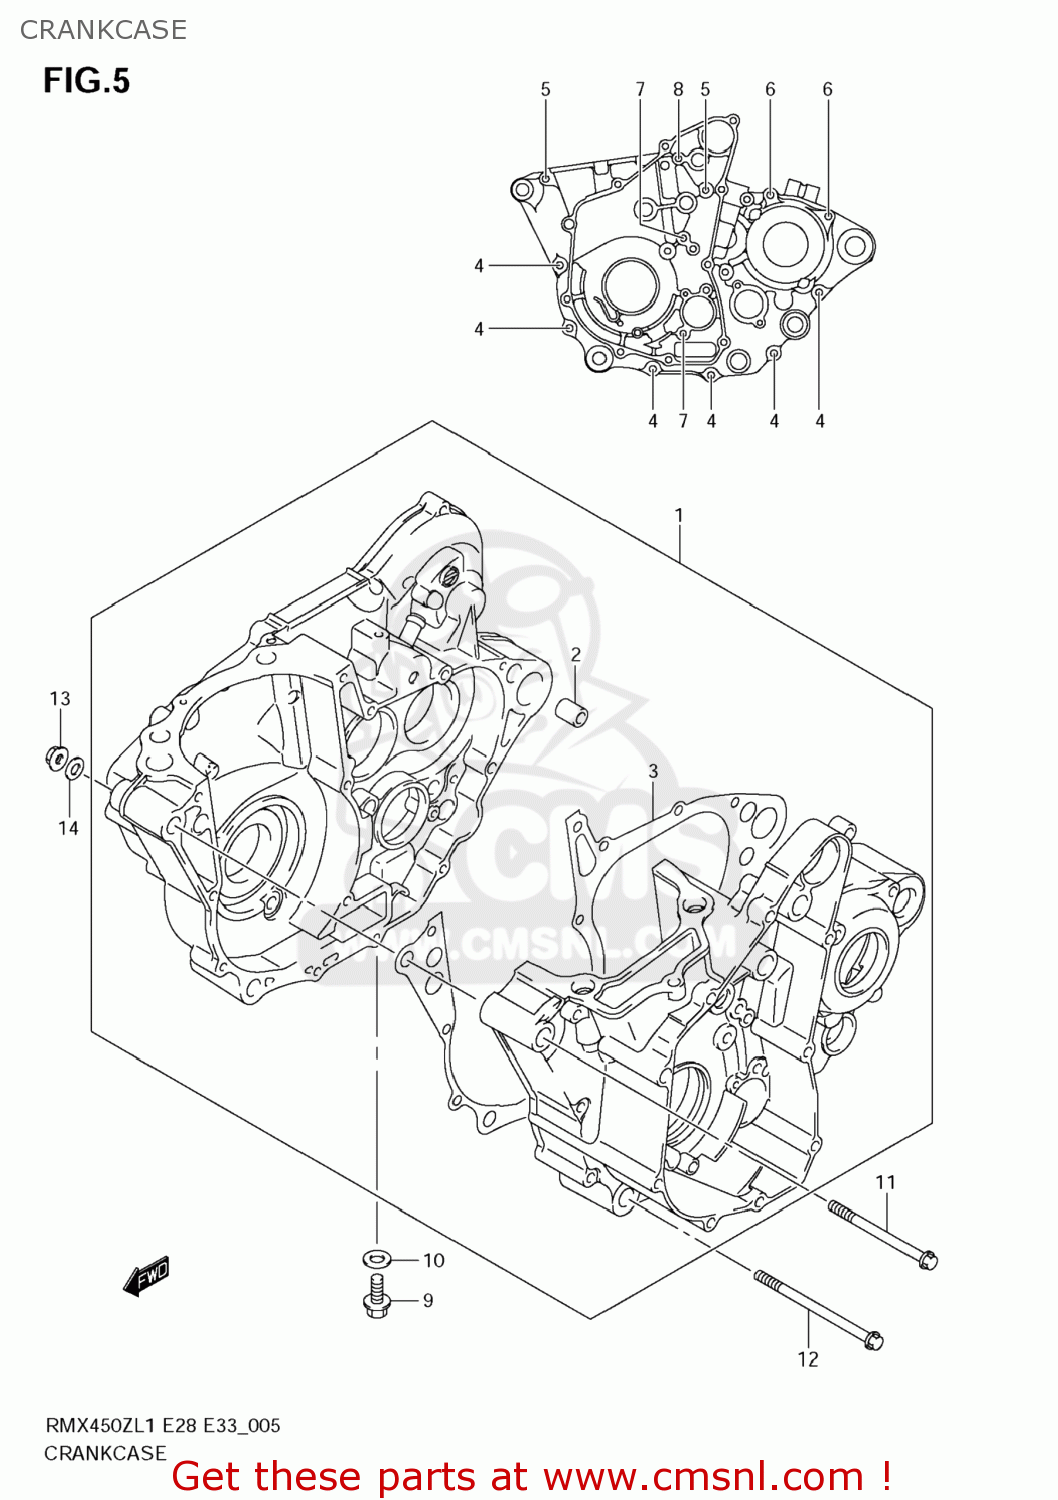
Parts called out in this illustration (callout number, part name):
1	CRANKCASE SET
2	PIN(10.4X13X18)
3	GASKET,CRANKCASE (NAS)
4	BOLT
5	BOLT
6	BOLT
7	BOLT
8	BOLT
9	BOLT(8X20)
10	GASKET(8.2X14X1) (NAS)
11	BOLT(10X120)
12	BOLT(10X125)
13	NUT
14	WASHER(10.5X22X2.3)
